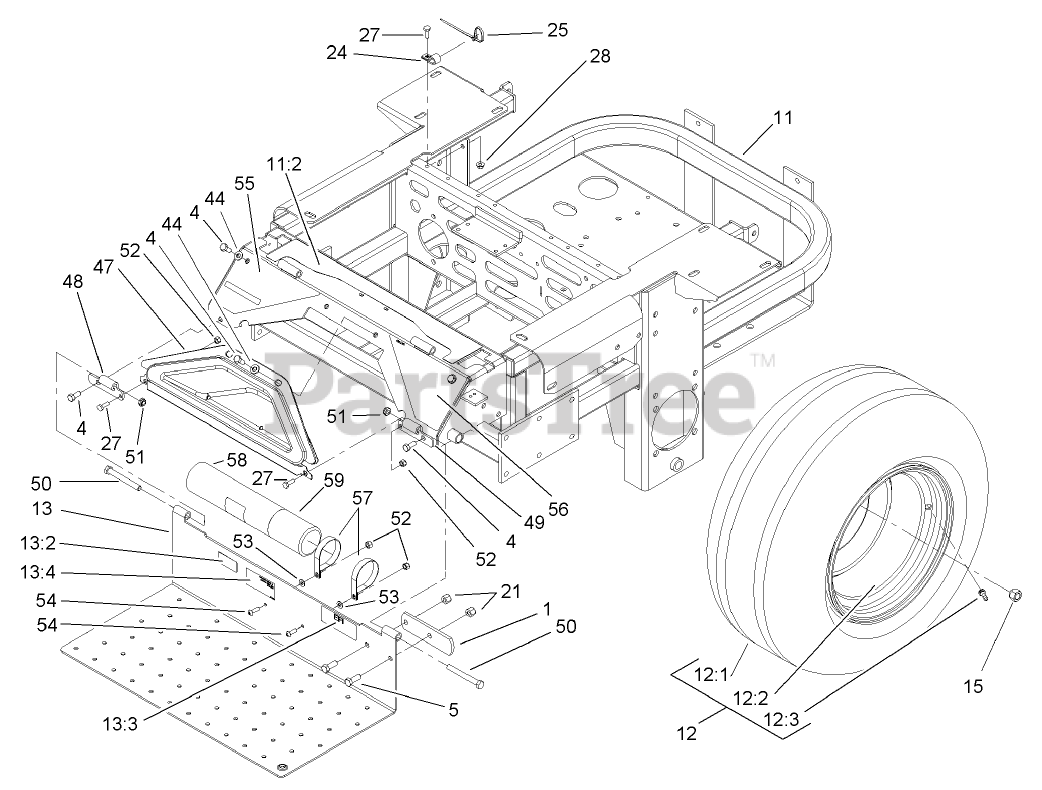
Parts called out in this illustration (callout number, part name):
1	STOP-BRAKE, PARK
4	SCREW-HH
5	SCREW-HH
11	Main Frame ASM
11:2	DECAL-CONSOLE, TOP
12	WHEEL AND TIRE ASM
12:2	WHEEL RIM
12:3	STEM-VALVE
13	FLOORPAN
13:2	Decal-Efi
13:3	DECAL-PROTECTION, EAR
13:4	Decal-Location, Manual
15	NUT-LUG
21	NUT-LOCK, NI
24	CLIP-LOOM
25	TIE-PLASTIC
27	SCREW-HH
28	NUT-HF
44	WASHER-FLAT
47	Pocket
48	Hinge-Floorpan, LH
49	Hinge-Floorpan, RH
50	SCREW-HH
51	NUT-LOCK, NI
52	NUT-LOCK, NI
53	WASHER-FLAT
54	SCREW-PRH
55	Decal-Warning
56	Decal-Danger
57	R-Clamp
58	TUBE-MANUAL
59	CAP-HOUSING
